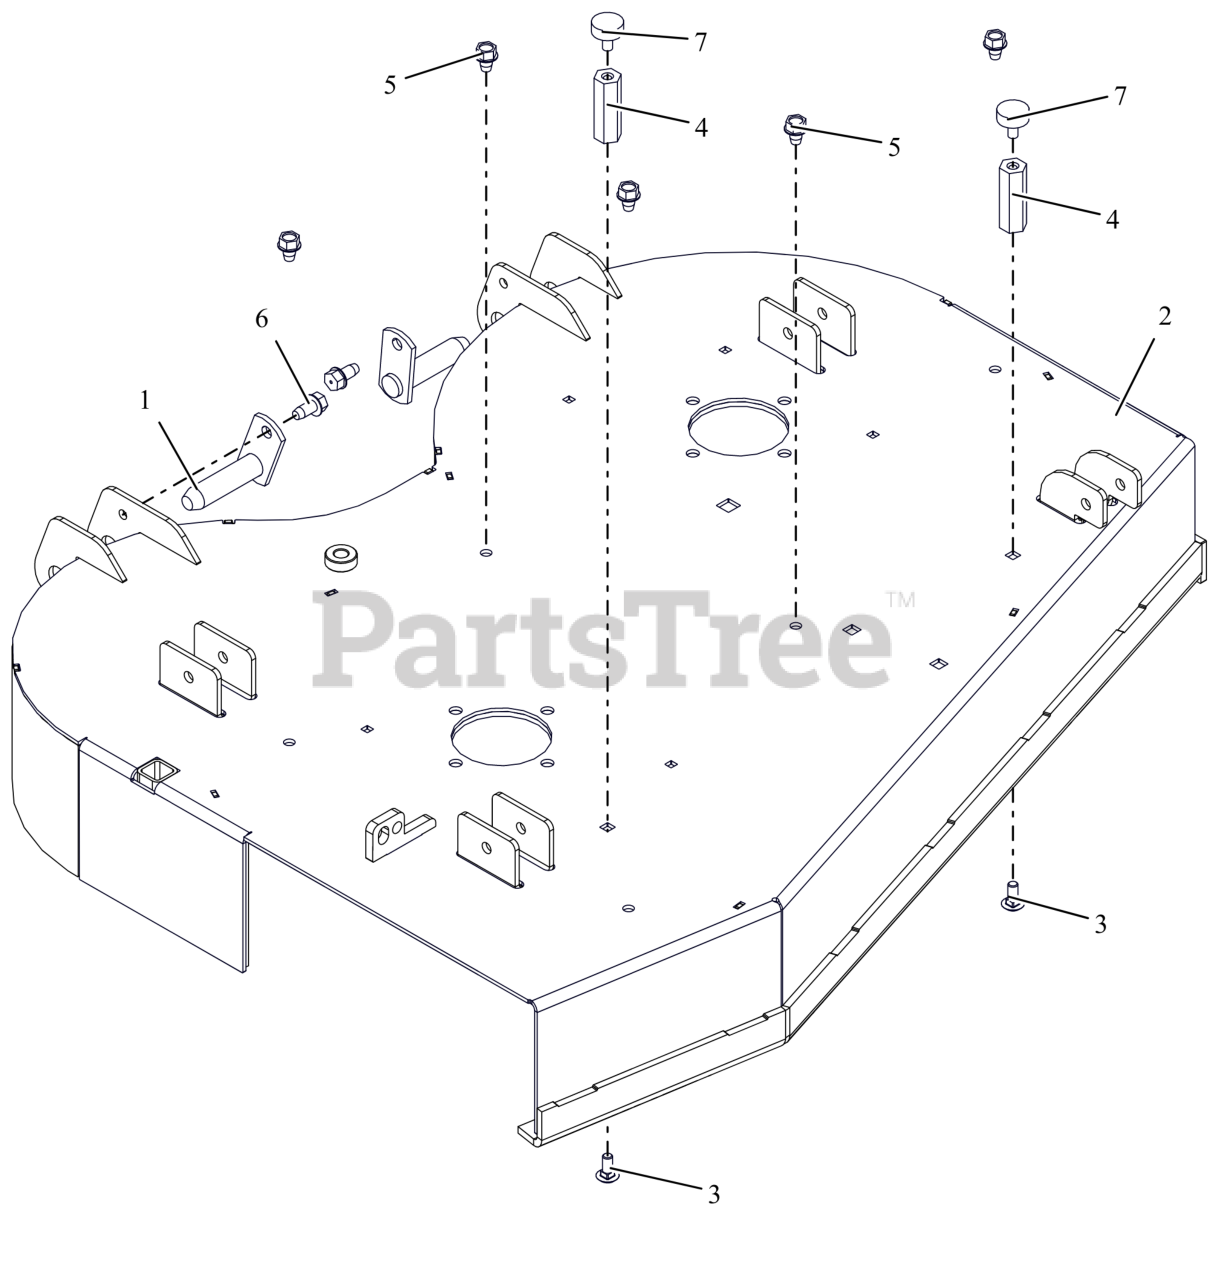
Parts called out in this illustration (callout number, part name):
1	WLDMT, MOWER MTG. PIN (BLACK)
2	KIT, 36" DECK PRO-WALK W/ DECALS (RED)
3	BTL,RHSN .313-18 X 0.75 G5 ZCC LT
4	NUT, .31-18X2.25 LG COUPLING
5	SCR,TAP .375-16X.50 HWH TR ZCC
6	SCR,TAP .375-16X.75 HWH TR ZCC
7	BUMPER, RUBBER
